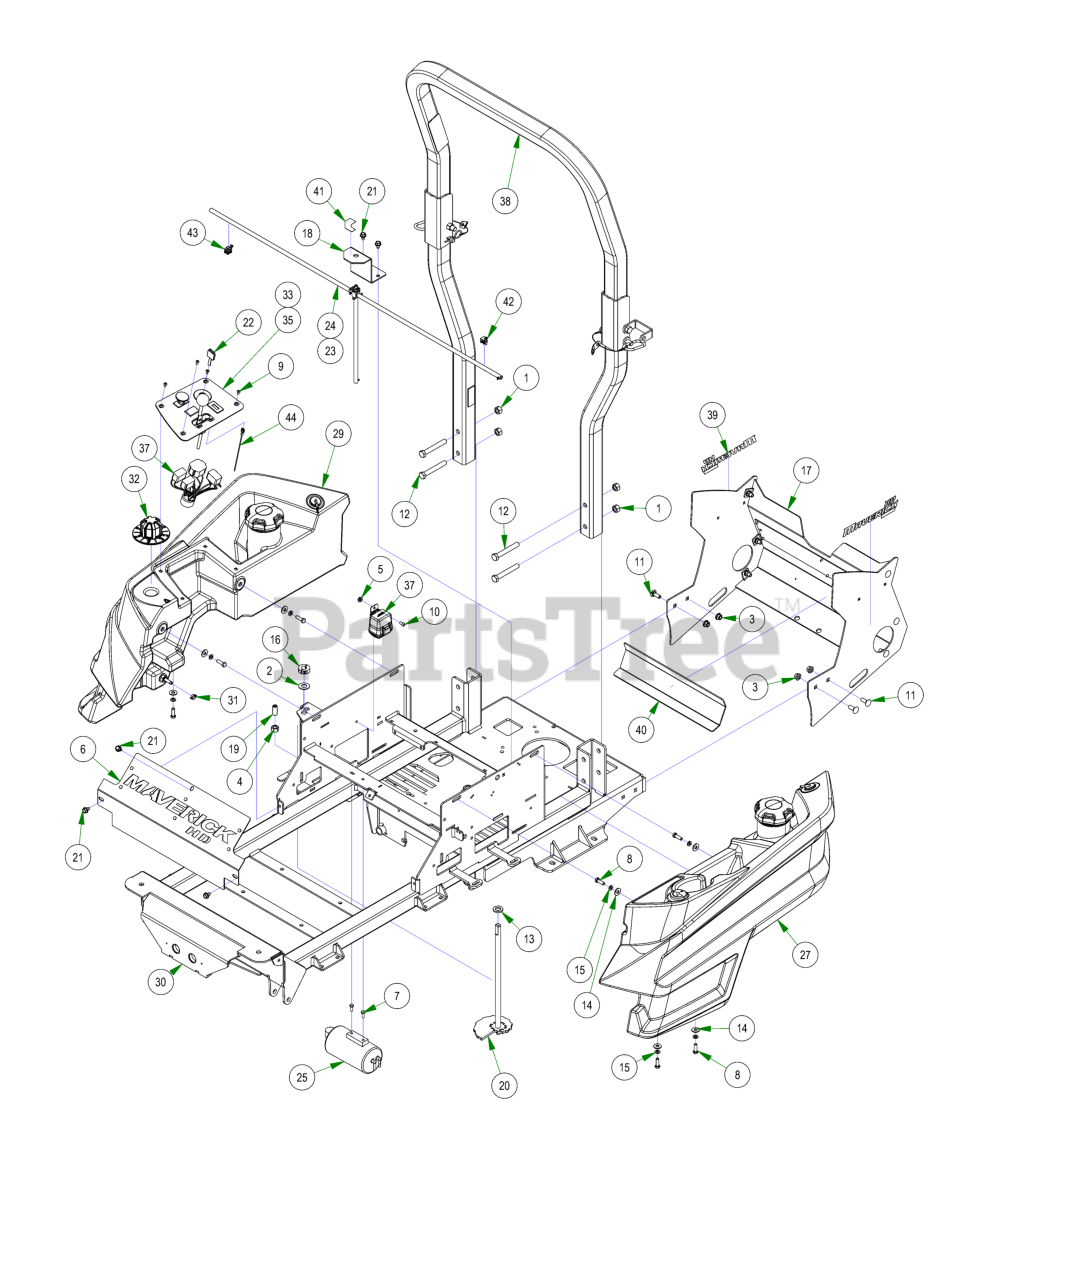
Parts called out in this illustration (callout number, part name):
1	1/2-13 HEX 2-WAY REVERSIBLE CENTER LOCKNUT Grade B ZINC
2	.625 ID x 1.250 OD x .062 THK F/W Nylon
3	3/8-16 NYLON INSERT FLANGE LOCKNUT (GR.F) ZINC
4	1/2-13 HEX NUT ZINC
5	1/4-20 HEX SERRATED FLANGE NUT HARD/ZINC
6	Maverick HD Cooler Cover
7	M6-1.0 X 16MM DIN 933 HEX TAP BOLT (CL 8.8) ZINC
8	5/16-18 X 1 HEX CAP SCREW (GR.5) ZINC
9	10-32 X 3/8 BUTTON SOCKET CAP SCREW 18-8 STAINLESS
10	1/4-20 X 1/2 BUTTON SOCKET CAP SCREW 18-8 STAINLESS
11	3/8-16 X 1 CARRIAGE BOLT (GR.5) ZINC
12	1/2-13 X 3-1/2 HEX CAP SCREW (GR.5) ZINC
13	.635 ID X 1.120 OD X .140 THICK FLAT WASHER NYLON
14	5/16 USS FLAT WASHER (7/8 OD) ZINC
15	5/16 SPLIT LOCKWASHER ZINC
16	5/8" Split Collar
17	2022 Maverick Rear Cover Assembly
18	Fuel Shut Off Mounting Plate
19	Dial Rod Plunger
20	ZT Deck Height Bar Assembly
21	5/16-18 X 1/2 HWH unslot (F) tcs zinc
22	Ignition Key
23	2023 Maverick HD Fuel Line with Shutoff
24	2023 Maverick HD Fuel Line with Shutoff
25	2023 HD Kohler/Kawasaki EPA Canister Assembly
26	2023 Maverick HD Honda EPA Canister Assembly
27	2021 Maverick Left Side Tank
28	Fuel Pick-up for 067-2021-00
29	2022 Maverick HD RH Fuel Tank
30	2023 Maverick Frame - Painted
31	2 EAR CLAMP 12.5mm-15mm
32	MZ/ZT Deck Height Dial
33	Maverick HD EFI Control Panel Assy
34	2022 Maverick HD Honda Control Panel Assembly
35	2023 Control Panel Assembly
36	Honda E-Throttle Adapter
37	2024 Wiring Harness with Clips
38	2016 2x2 ROPS
39	Maverick HD Back Plate Decal
40	Heat Shield (Fiberglass Adhesive)
41	Maverick HD Shut Off Valve Decal
42	Edge Clip With Ziptie
43	Edge Clip With Ziptie
44	2017 MZ/ZT/MAV Tach Wire Assy
